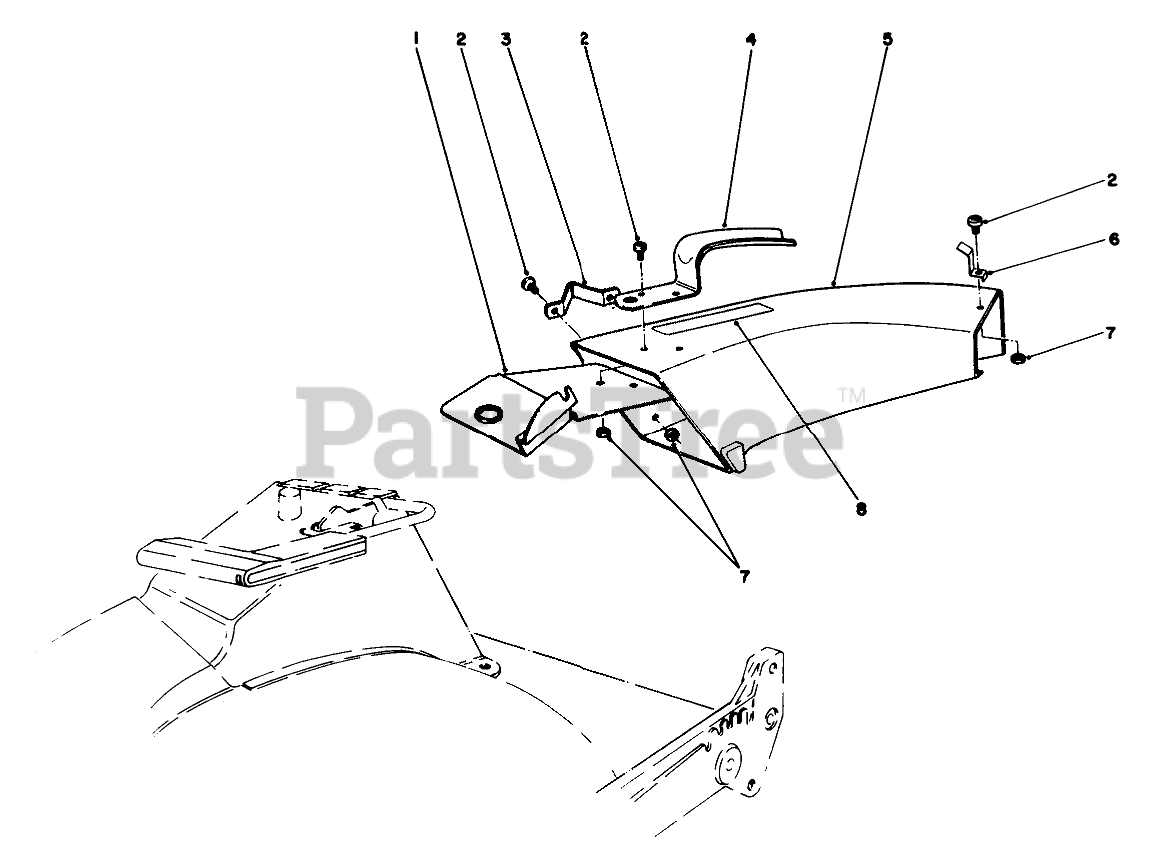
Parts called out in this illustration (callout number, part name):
1	Plate-Discharge Chut
2	10-24 X 5/8 PAN HD MS
3	SIDE BRACKET
4	CHUTE HANDLE
5	Chute-Discharge (Incl. Ref. #8)
7	NUT-LOCK, NI
8	DECAL CAUTION
